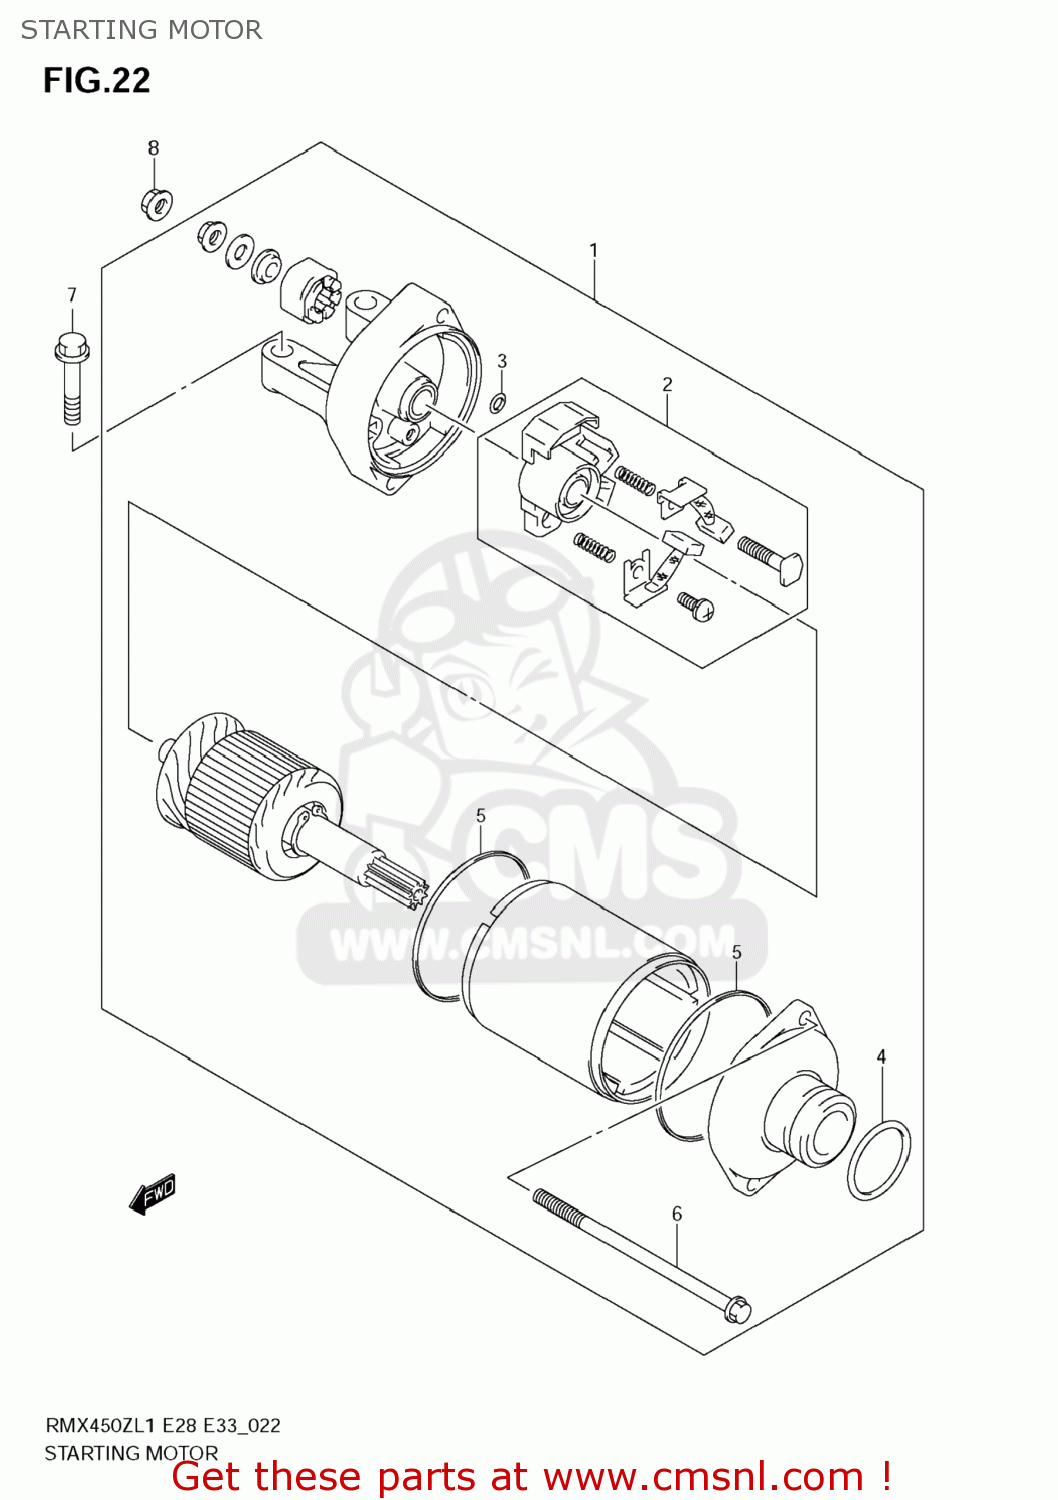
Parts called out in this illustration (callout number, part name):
1	MOTOR ASSY,STARTING
2	BRUSH HOLDER SET
3	O RING
4	O RING
5	SQUARE RING
6	BOLT
7	BOLT(6X25)
8	NUT
